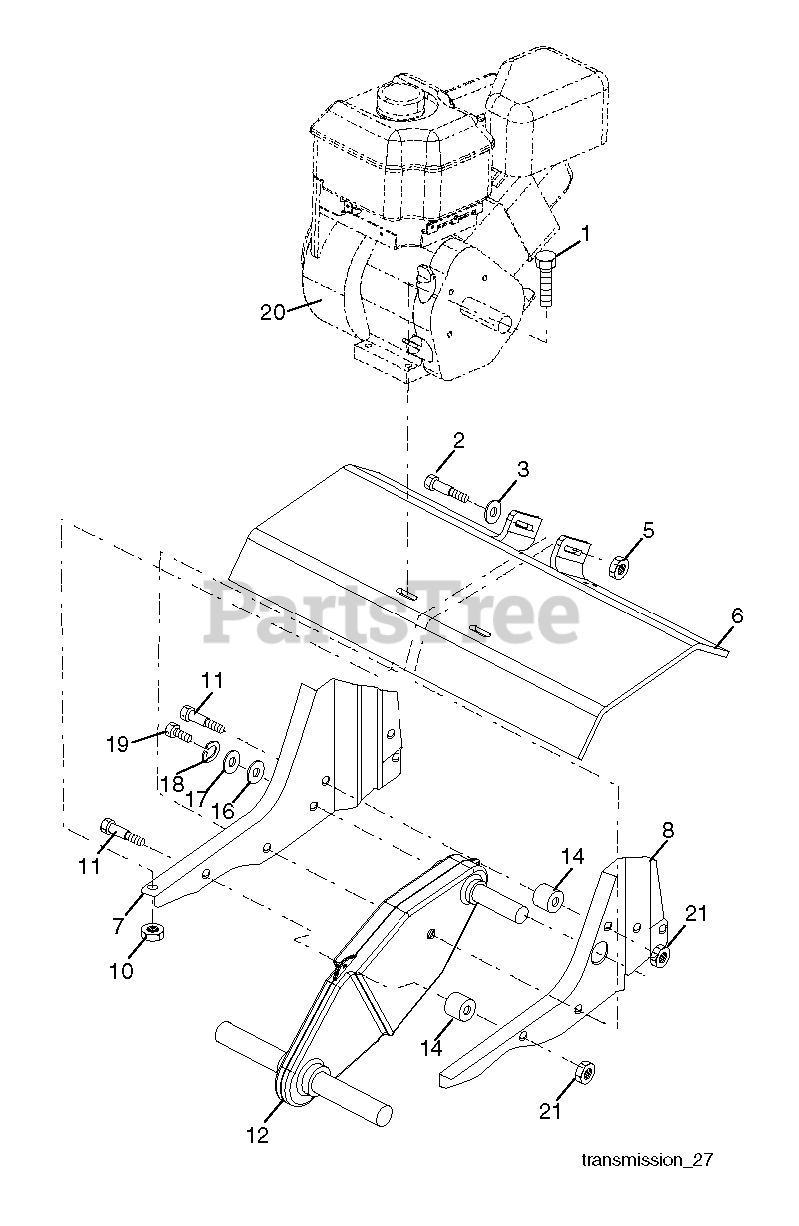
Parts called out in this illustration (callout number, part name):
1	BOLT
2	Bolt, Hex 3/8-16 x 3-1/4
3	WASHER
5	NUT LOCK FLG 3/8-16 UNC
6	SHIELD.PNT.TINE.24".ORANGE
7	BRACKET.ENGINE.RH.TILLER.BLACK
8	BRACKET.ENGINE.TILLER.BLACK
10	LOCKNUT-FLANGE 5/16-18
11	BOLT, HEX HEAD 5/16-18 X 2.5
12	TRANSMISSION.ASM.W/1".D-SHAFT
14	SPACER.SPLIT.327 X 1.00
16	REPL BY 819 09 14-16
18	LOCKWASHER
19	Bolt, Hex 1/4-28 x 3/4 Gr. 5
21	NUT.LOCK.5/16-18
